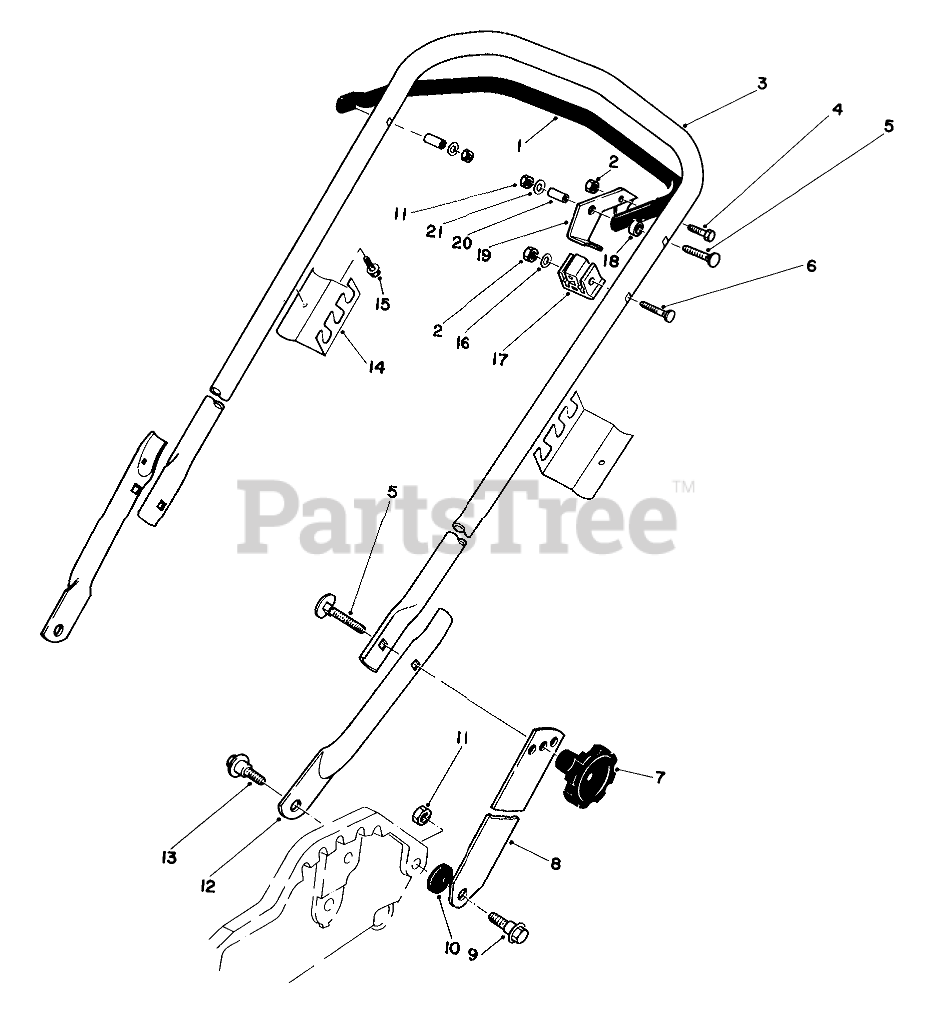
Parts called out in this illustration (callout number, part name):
1	CONTROL BAR
2	NUT-LOCK, NI
3	Handle-Upper
4	SCREW-HH
5	5/16-18 X 2 HNDLE SCREW
6	SCREW-HANDLE
8	Handle Latch
9	SCREW-SHOULDER
10	SPACER
11	NUT-LOCK, NI
12	Hand-Lower
13	SCREW-SHOULDER
14	Bag Support
15	SCREW-HWHTF
16	WASHER-FLAT
17	SUPPORT-CABLE
18	Nylon Spacer
19	Lever-Control
20	Spacer
21	WASHER-PLAIN
